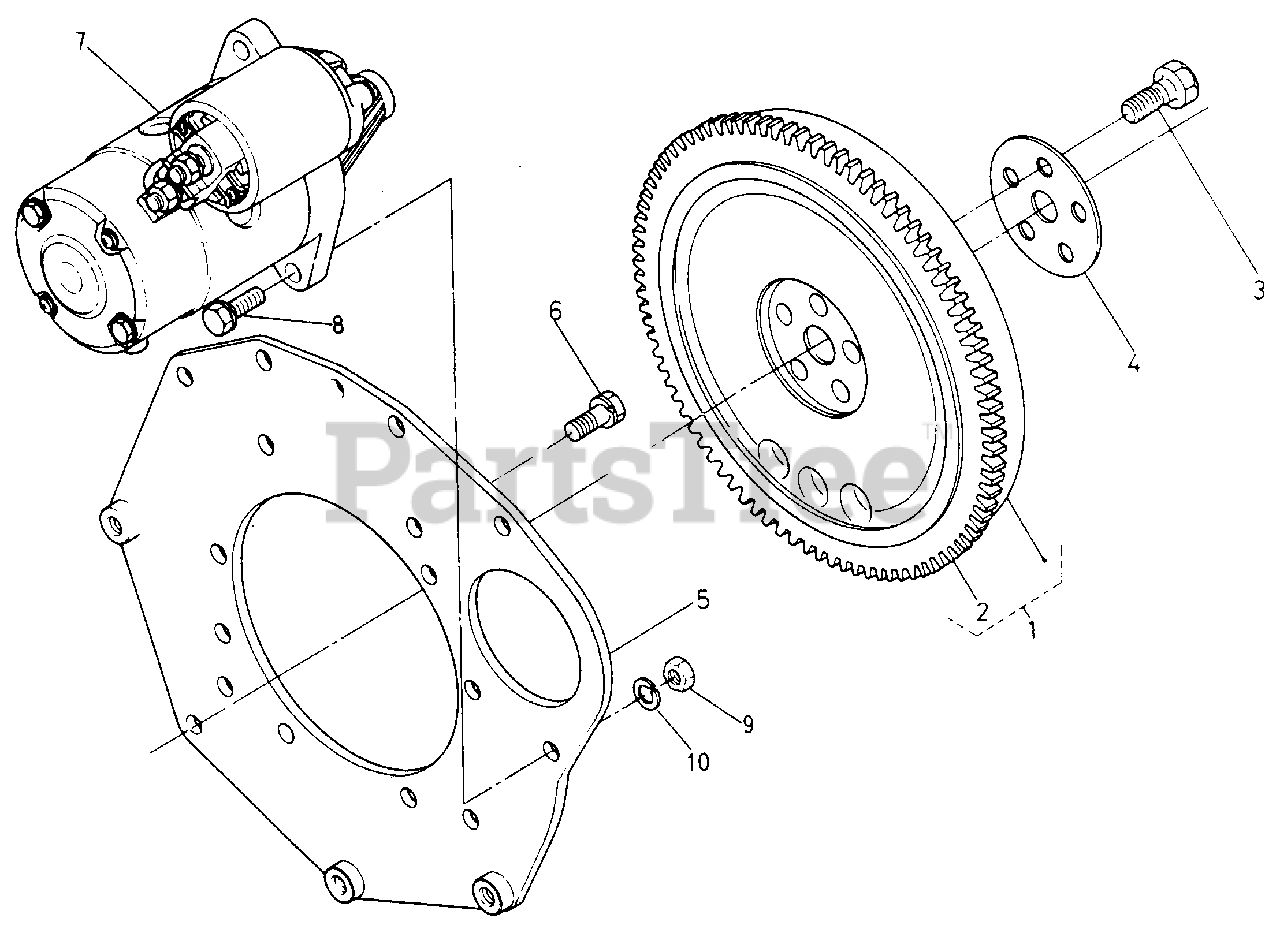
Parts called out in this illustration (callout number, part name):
1	Flywheel Assy
3	Bolt, Flywheel
4	Washer, Flywheel
5	Plate, Rear End
6	Bolt, M8 X 16 Class 8.8
7	Starter
9	Nut, M8 Class 8
10	Washer, 8MM Lock
